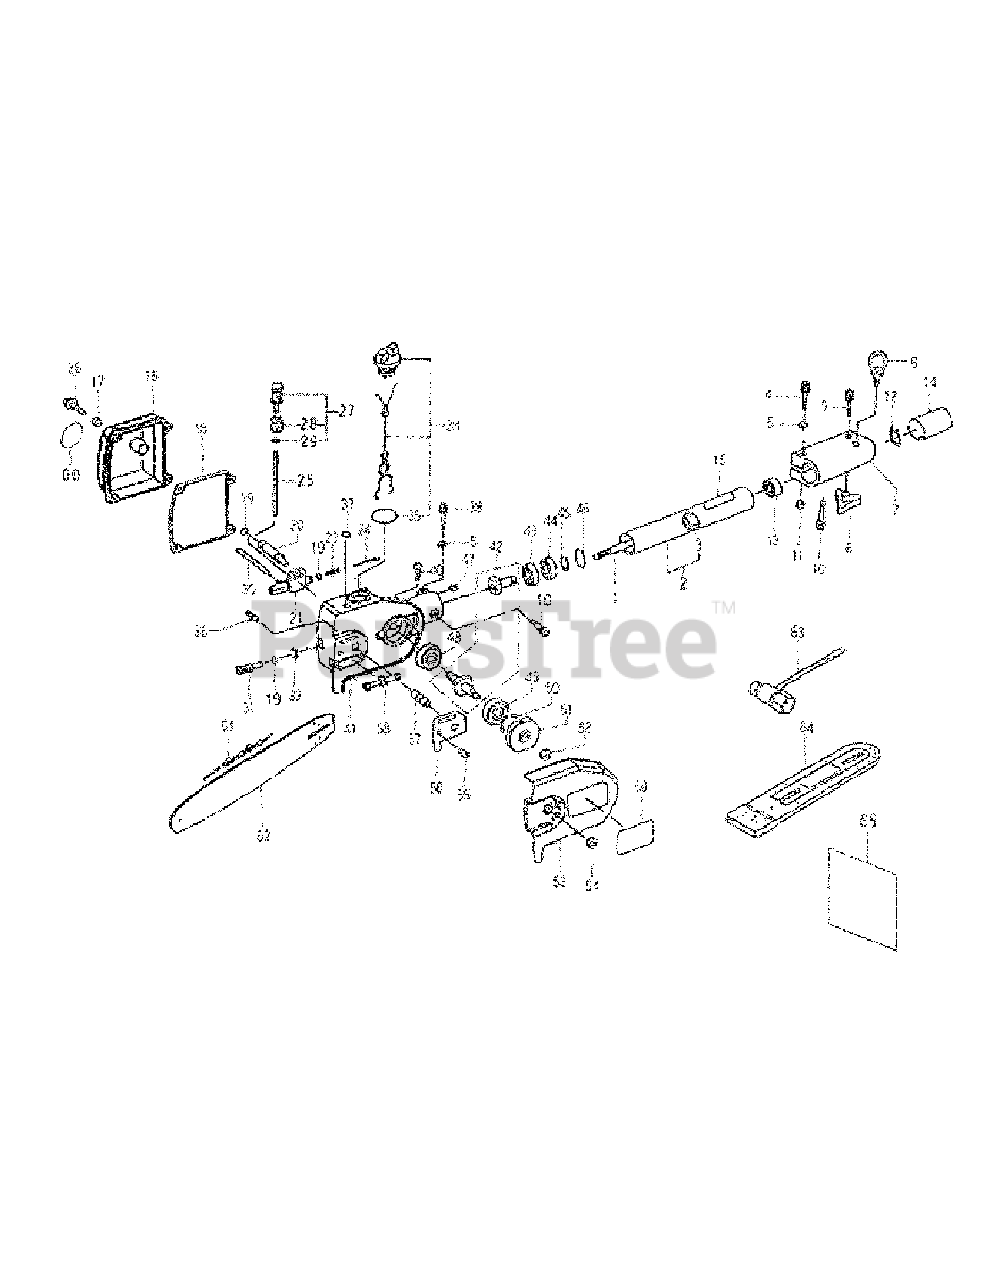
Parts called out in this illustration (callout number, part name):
1	Shaft, Drive
2	Pipe complete
5	Spring Washer
13	Ball Bearing
15	Caution Plate
16	Cover, Oil Tank
21	Pump, Lubricating Oil
24	Piston, Oil Pump
27	Filter Assembly Oil
28	Filter, Oil
29	Washer
31	Adjuster, Oil Pump
34	Cap, Oil Fill
42	Gear Assembly
43	Ball Bearing
44	Ball Bearing
48	Ball Bearing
49	Ball Bearing
56	Plate, Guide
60	Caution Plate
61	Chain; 9.52 mm (3/8")
62	Bar, Chain 250mm (10")
64	Cover, Chain
